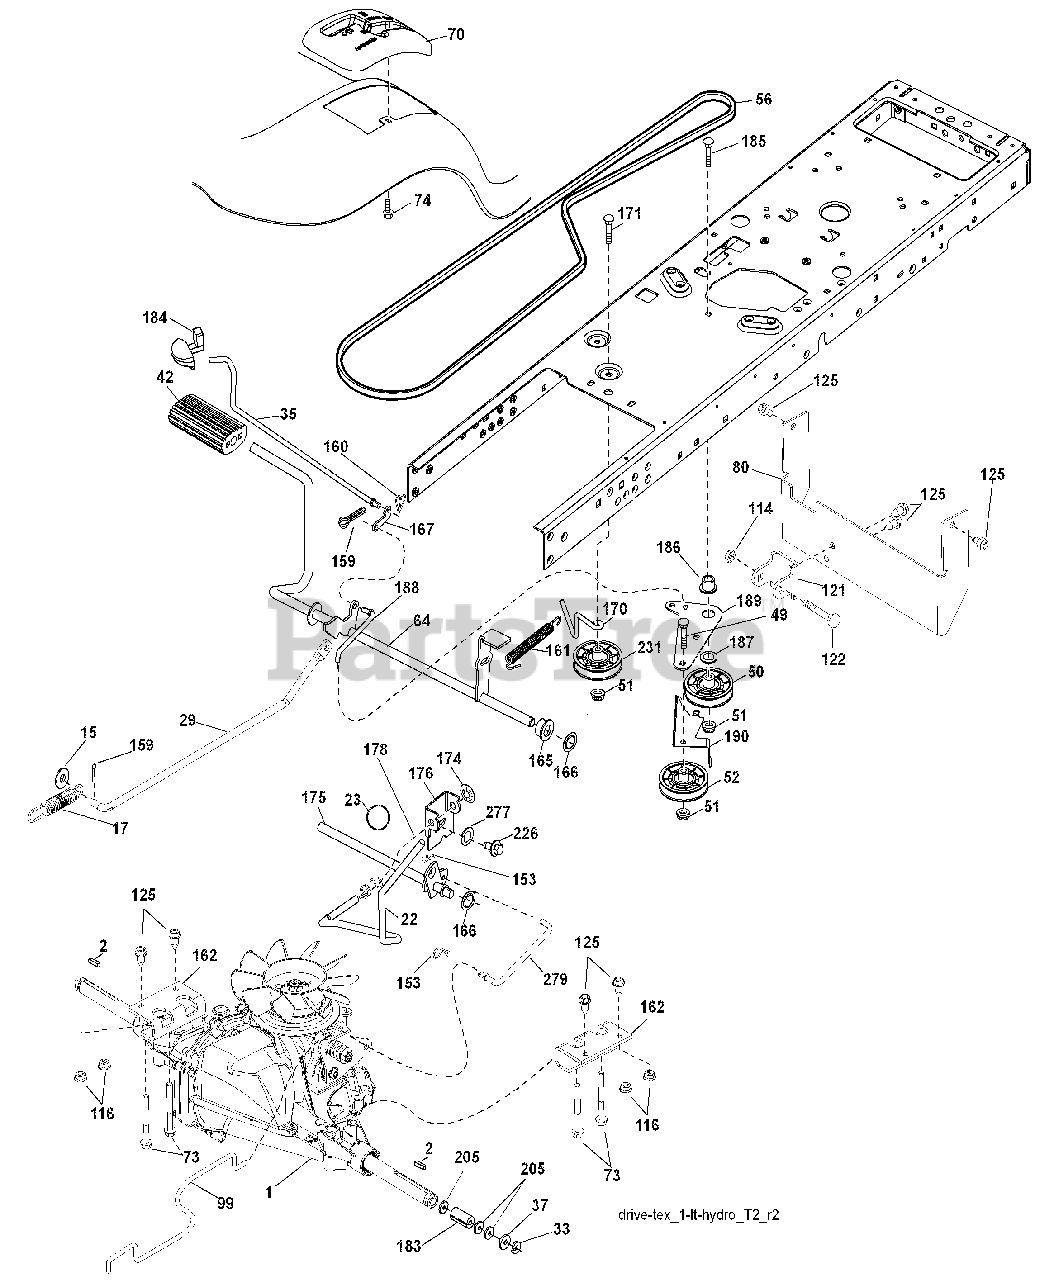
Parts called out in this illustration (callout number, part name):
2	Key Square
15	Washer 13/32 x 13/16 x 16 Ga.
17	Spring, Brake
22	Rod Shift
23	Knob
29	Rod, Brake
33	Ring E
35	Rod, Brake, Park
37	Washer 25/32 x 1-1/4 x 16 Ga.
42	Cover, Foot Pedal
49	Bolt
50	Pulley Idler Flat
51	Lock Nut 3/8-16
52	Idler V-Groove 910" Offset
56	V-Belt, Drive
64	Shaft Asm. Pedal Brake Control
70	Console
73	Bolt Hex 5/16-18 Gr. 5
74	Screw 1/4 x 1/2
80	Strap Torque
99	Rod Spring Bypass
114	Nut Lock 5/16-18 UNC
116	Nut Lock Hex Flange 5/16-18
121	Bracket Strap Torque
122	Bolt 5/16-18 x 2.50
125	Screw 5/16-18 x 3/4
153	Retainer Spring 1"
159	Pin Cotter 1/8 x 3/4
160	Retainer Clip
161	Spring, Return, Clutch
165	Bushing
166	Nut Push .625
167	Latch Brake Parking
170	Keeper Belt Centerspan
171	Bolt
174	Nut Push
175	Shaft Asm Shift
176	Arm Clevis Rod Shift
178	Spring Shift
183	Spacer Axle
184	Handle Parking Brake
185	Bolt
186	Spacer Retainer
188	Link Clutch Ground Drive
189	Bellcrank Ground Drive
190	Keeper Bellcrank Ground Drive
205	Washer 25/32 x 1-5/8 x 16 Ga.
226	Bolt 7/16-14 x 1 Gr 5
227	Washer Serrated
231	Idler V-Groove 1.688" Offset
279	Link Shift
